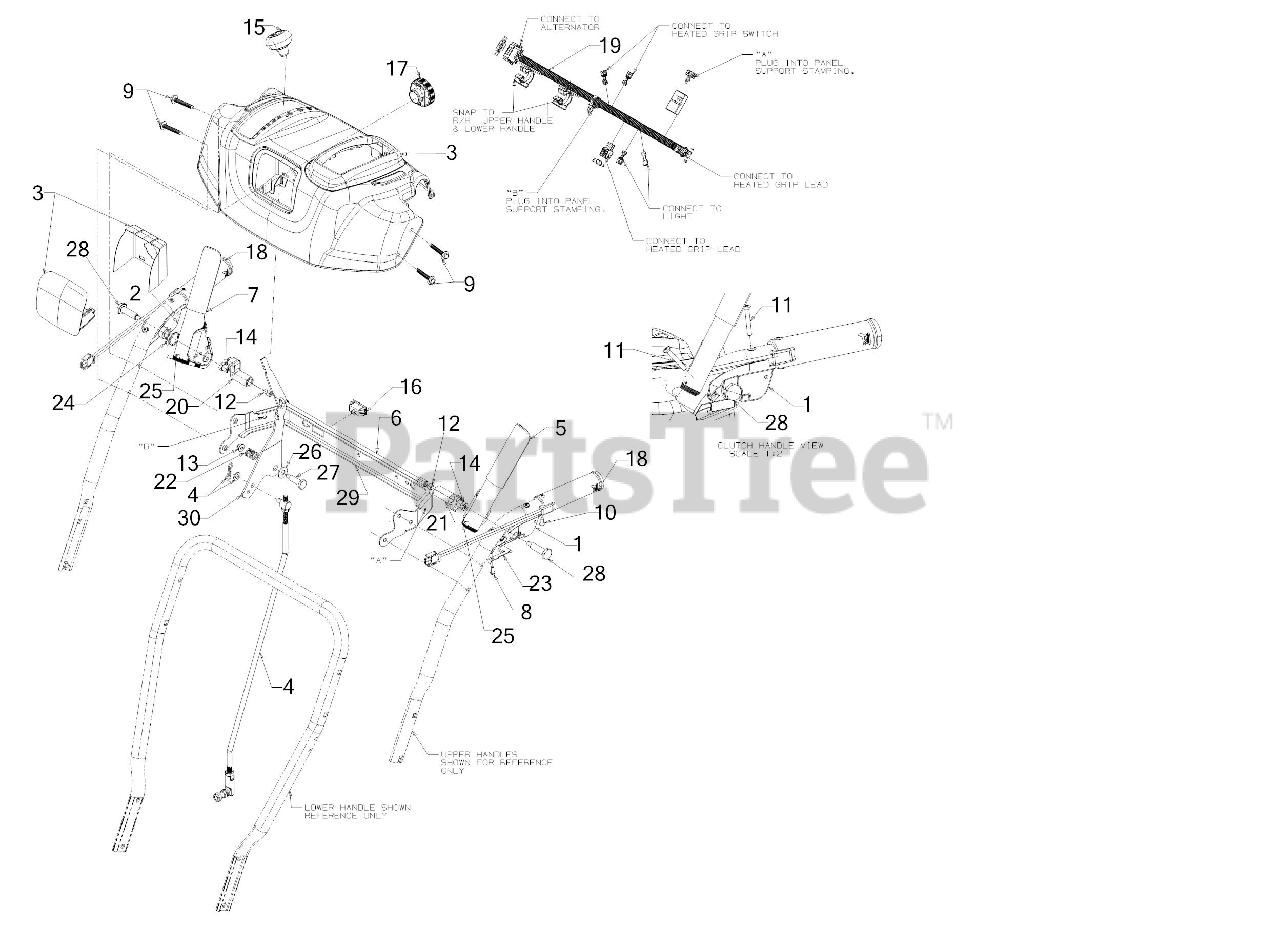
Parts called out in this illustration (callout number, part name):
1	CLUTCH LOCK HANDLE ASSEMBLY (LH)
2	CLUTCH LOCK HANDLE ASSEMBLY (RH)
3	HANDLE PANEL ASSEMBLY (BLACK)
4	SHIFT ROD ASSEMBLY
5	HANDLE ASSEMBLY (LH)
6	PIVOT ROD
7	ENGAGEMENT HANDLE ASSEMBLY (RH) (BLACK)
8	SCREW #8-16 x .50
9	SCREW 1/4-20 x 1.625
10	SCREW #10-16 x .625
11	SCREW #10-24 x 1.375
12	SCREW 1/4-20 x .50
13	FLANGE LOCK NUT
14	HEX NUT W/PATCH
15	SHIFT KNOB
16	HEATED GRIP SWITCH
17	HEADLIGHT ASSEMBLY
18	HARNESS
19	HEATED GRIPS HARNESS
20	LOCK PLATE
21	CLUTCH LOCK CAM
22	COMPRESSION SPRING
23	CLUTCH SPRING
24	TORSION SPRING
25	RUBBER BUMPER
26	FLAT WASHER
27	SHOULDER SCREW
28	SHOULDER SCREW .437 x 1.345 1/4-20
29	HANDLE SUPPORT BRACKET
30	SHIFT LEVER
